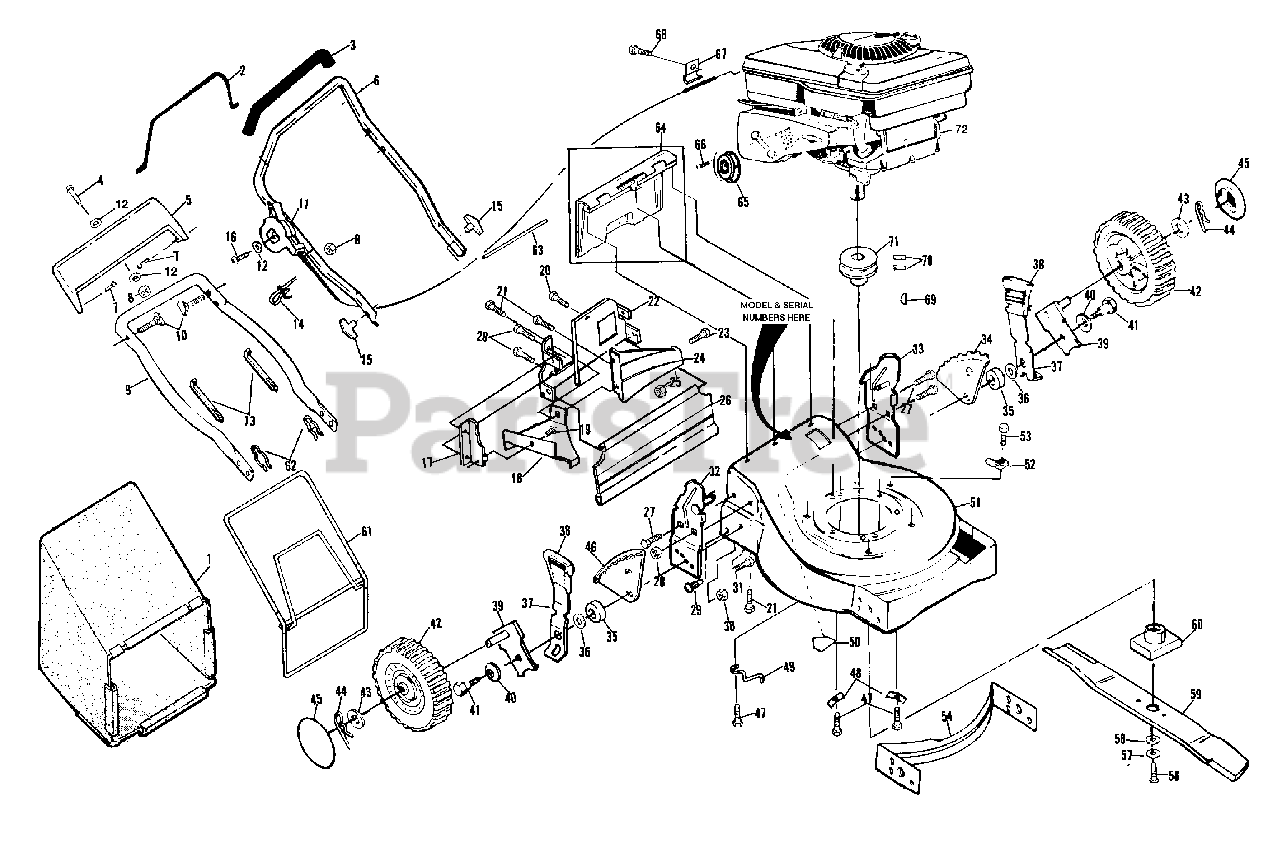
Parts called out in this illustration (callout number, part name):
1	Grass Bag Assembly
2	Control Bar
3	Handle Grip
4	Hex Washer Head Machine Screw 1/4-20 x 1-1/2
5	Trim Plate
6	Upper Handle
7	Self-tapping Screw #10-24 x 5/8
8	Locknut 1/4-20
9	Lower Handle
10	Handle Bolt
11	Throttle Control
13	Wire Tie
14	Rope Guide
15	Handle Knob
16	Round Head Screw 1/4-20 x 2-3/4
17	Side Baffle
18	Discharge Baffle
19	Hex Head Screw #10-24 x 1/2
20	Self-tapping Screw #10-24 x 3/8
21	Hex Tapping Screw 1/4-20 x 1/2
22	Back Plate
23	Thread Screw #10-24 x 1/2
24	Rear Baffle
26	Rear Skirt
27	Thread Cutting Screw 5/16-18 x 3/4
28	Locknut
29	Hinge Screw
30	Locknut
31	Carriage Bolt
32	Handle Bracket Assembly (Right)
33	Handle Bracket Assembly (Left)
34	Wheel Adjusting Bracket (LR)
35	Spacer
37	Selector Spring
38	Selector Knob
39	Axle Arm Assembly
40	Belleville Washer
41	Shoulder Bolt 3/8-16
42	Wheel & Tire Assembly 9.0 x 2.0
44	Retainer Clip
46	Wheel Adjusting Bracket (RR)
47	Thread Rolling Screw 3/8-16 x 1
48	Engine Washer
49	Belt Snubber
50	Danger Decal
51	Lawn Mower Housing
52	Guide Clip (Housing)
53	Hex Washer Head Screw #10-24 x 1/2
54	Front Baffle
56	Hex Head Screw 3/8-24 x 1-3/8 Gr. 8
57	Helical Lockwasher 3/8
58	Hardened Washer
59	22" Blade
60	Blade Adapter
61	Catcher Frame Assembly
62	Hairpin Cotter
65	Muffler Deflector
66	Screw #8-32 x 3/8
67	Cable Clamp
68	Thread Rolling Screw #10-32 x 5/8
69	Hi-Pro Key
70	Set Screw 1/4-20 x 5/16
71	Engine Pulley
